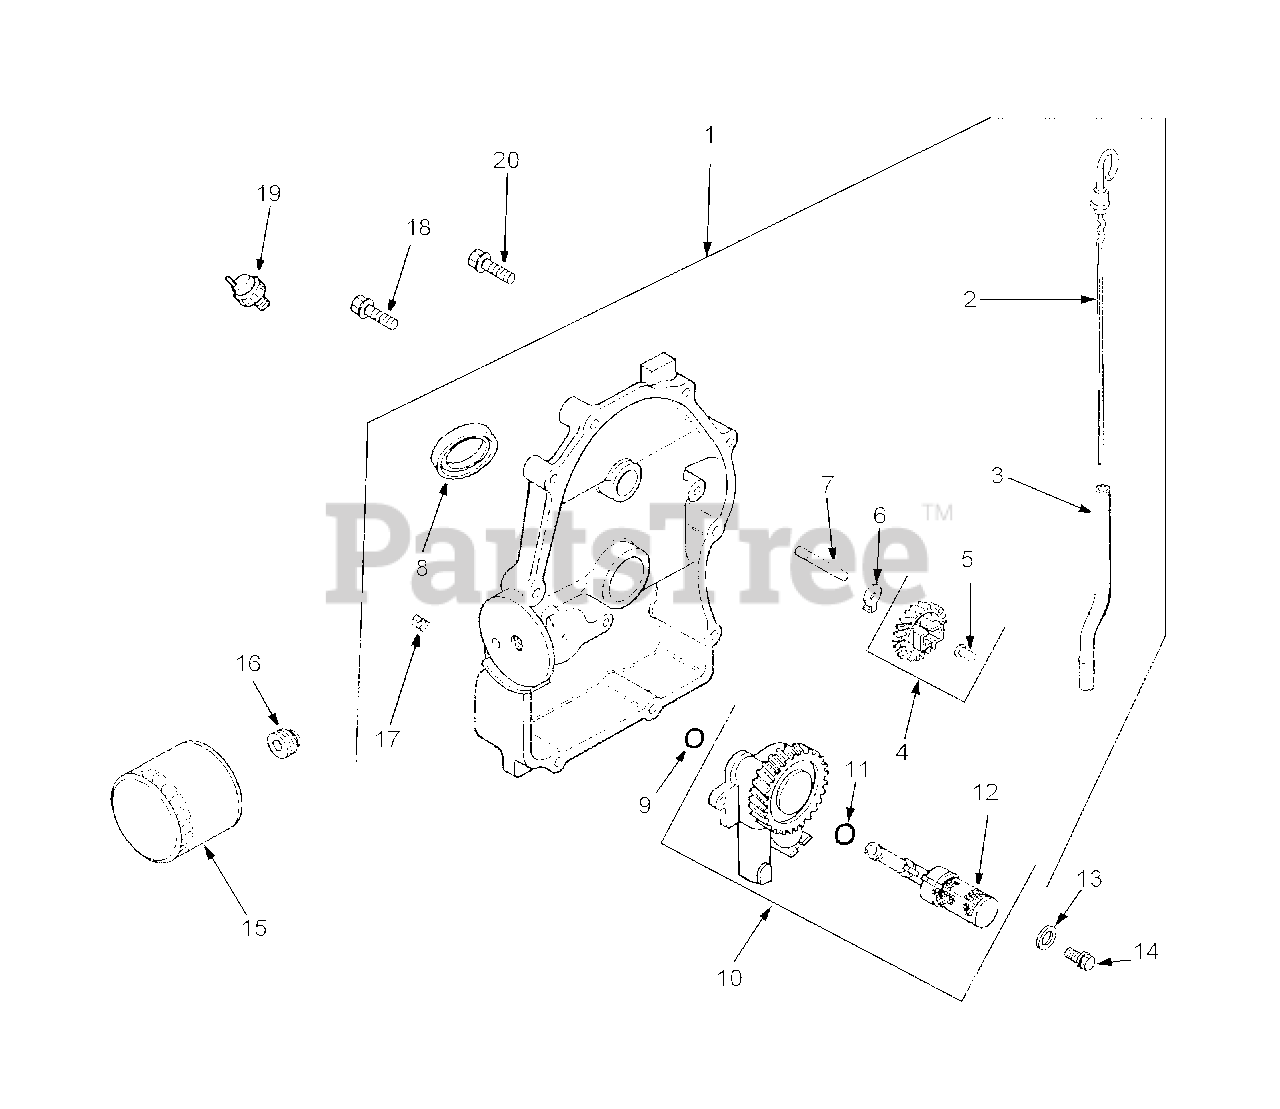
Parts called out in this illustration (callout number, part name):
1	Plate, Closure Assembly
2	Dipstick
3	Tube, Dipstick
4	Kit, Governor Gear
5	Pin, Governor Regulating
6	Tab, Locking
7	Shaft, Governor Gear
8	Seal, Oil (PTO End)
10	Oil Pump Assembly
11	O-Ring, Oil Pick-Up
12	Pick-Up, Oil
13	Washer, Plain
14	Screw, Hex Flange M6 x 1 x 25
15	Filter, Oil
16	Nipple, Oil Filter
17	Plug, Pipe 1/8"
18	Screw, Hex Flange M8 x 1.25 x 45
19	Switch, Pressure
20	Screw, Hex Flange M8 x 1.25 x 45
